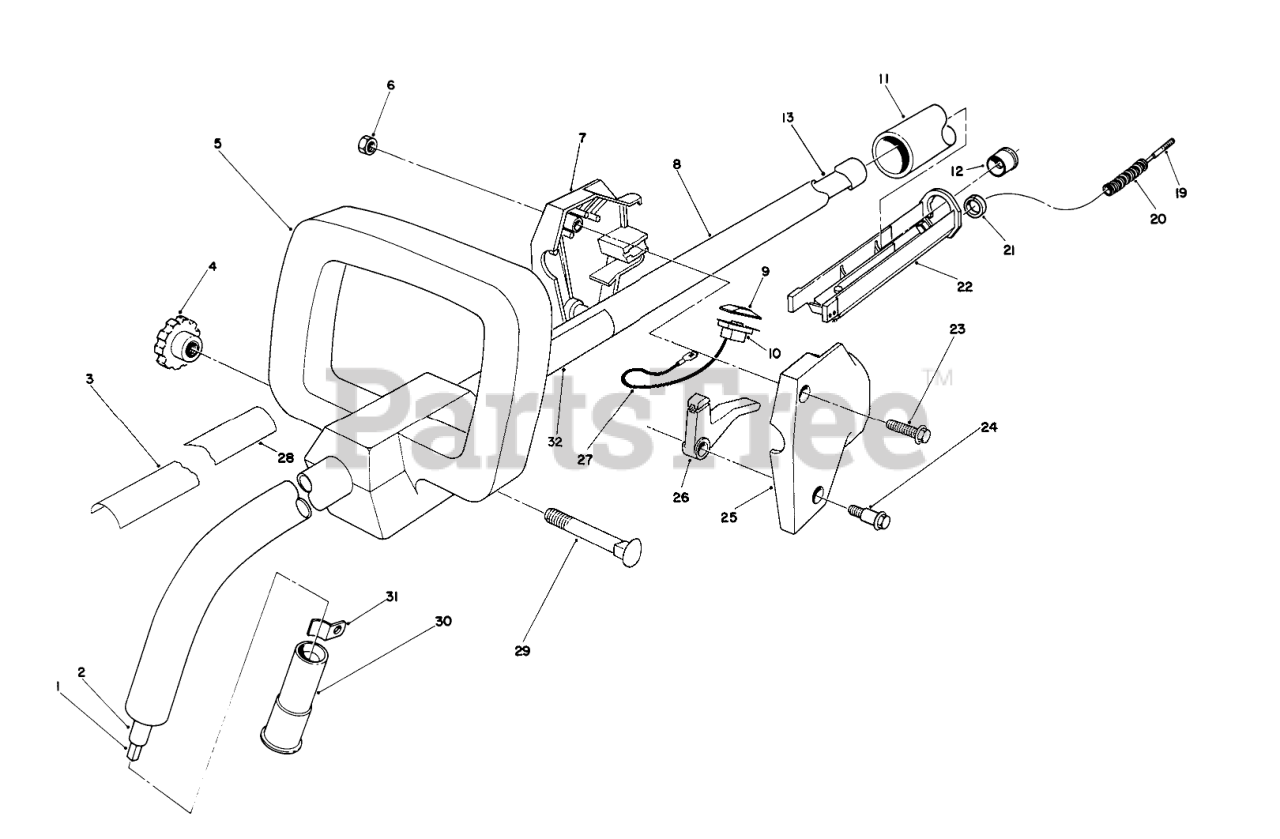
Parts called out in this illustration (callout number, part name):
1	FLEX SHAFT
2	FLEX SHAFT CASING
3	DECAL - TC 2010
5	SECONDARY HANDLE
6	NUT-LOCK, NI
7	RH HOUSING
8	Tube-Curved
9	SWITCH COVER
10	SWITCH
11	GRIP-RUBBER
12	BUSHING
13	Spacer
19	THROTTLE CABLE
20	CABLE COVER
21	RING FITTING
22	TROUGH
24	SCREW-SHOULDER
25	LH HOUSING
26	THROTTLE LEVER
27	WIRE ASM
28	Decal-Warning
29	BOLT-CARRIAGE
30	INSERT-POLE END
31	LOWER TUBE RETAINER
32	DECAL-INSTRUCTION
